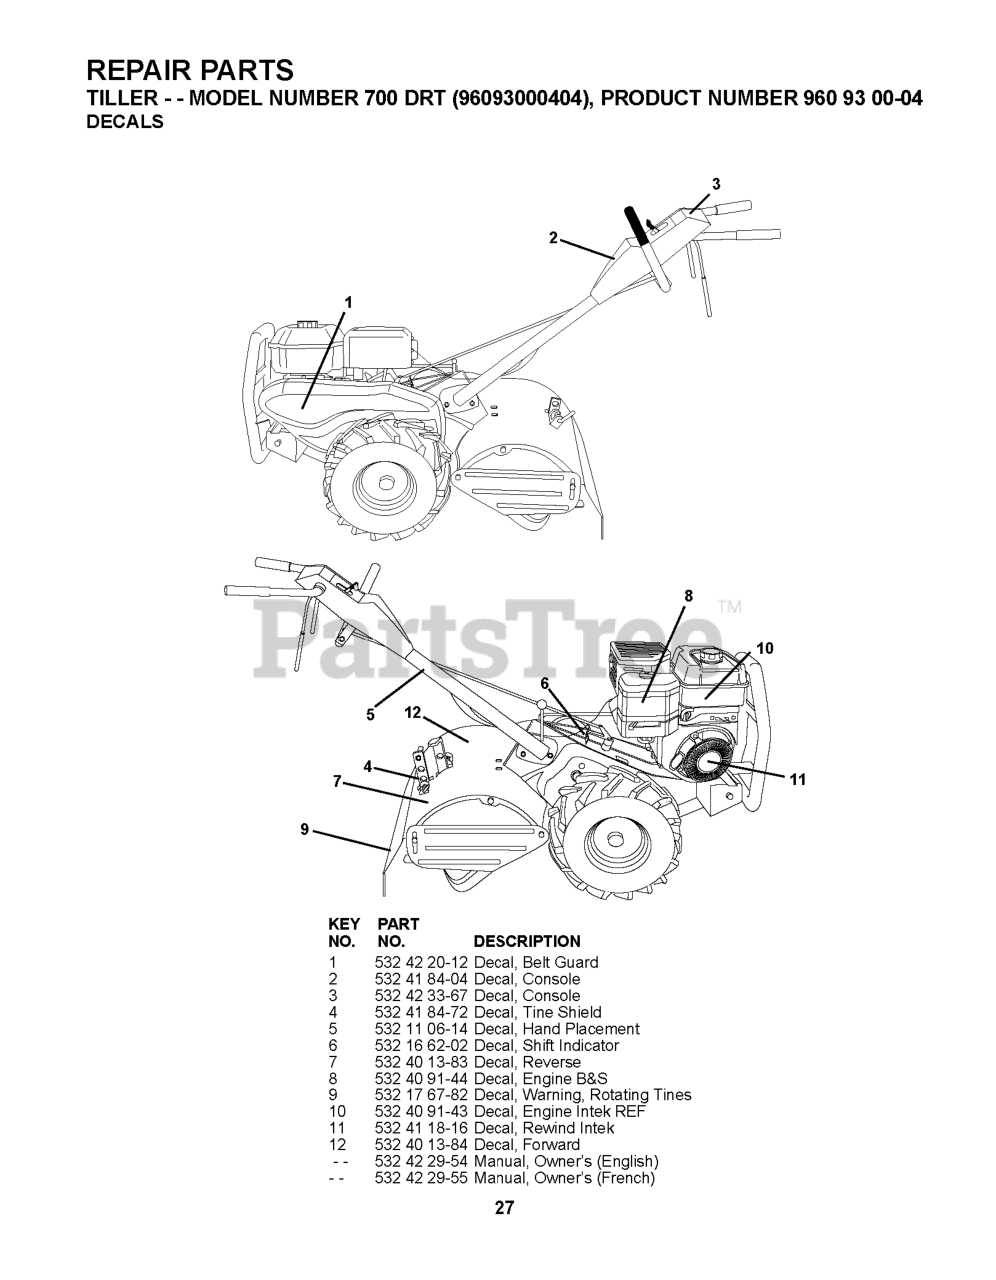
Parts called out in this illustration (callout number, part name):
1	DECAL.HOOD.LOGO.ORANGE.HUSQVAR
2	DECAL.CONSOLE.700DRT.HUSQ
4	DECAL.SHIELD.TN.DRT17.HUSQ.008
5	DECAL TI (2 2)
6	DECAL.SHIFT.INDICATOR.DRT
7	DECAL.REVERSE.HUSQ
8	DECAL.B&S.900.A/C.REF.277024
9	DECAL.DRT.WARN.ENG/F
10	DECAL.B&S.900.TANK.REF.276991
11	DECAL, REWIND STARTER, B&S
12	DECAL.FORWARD.HUSQ
